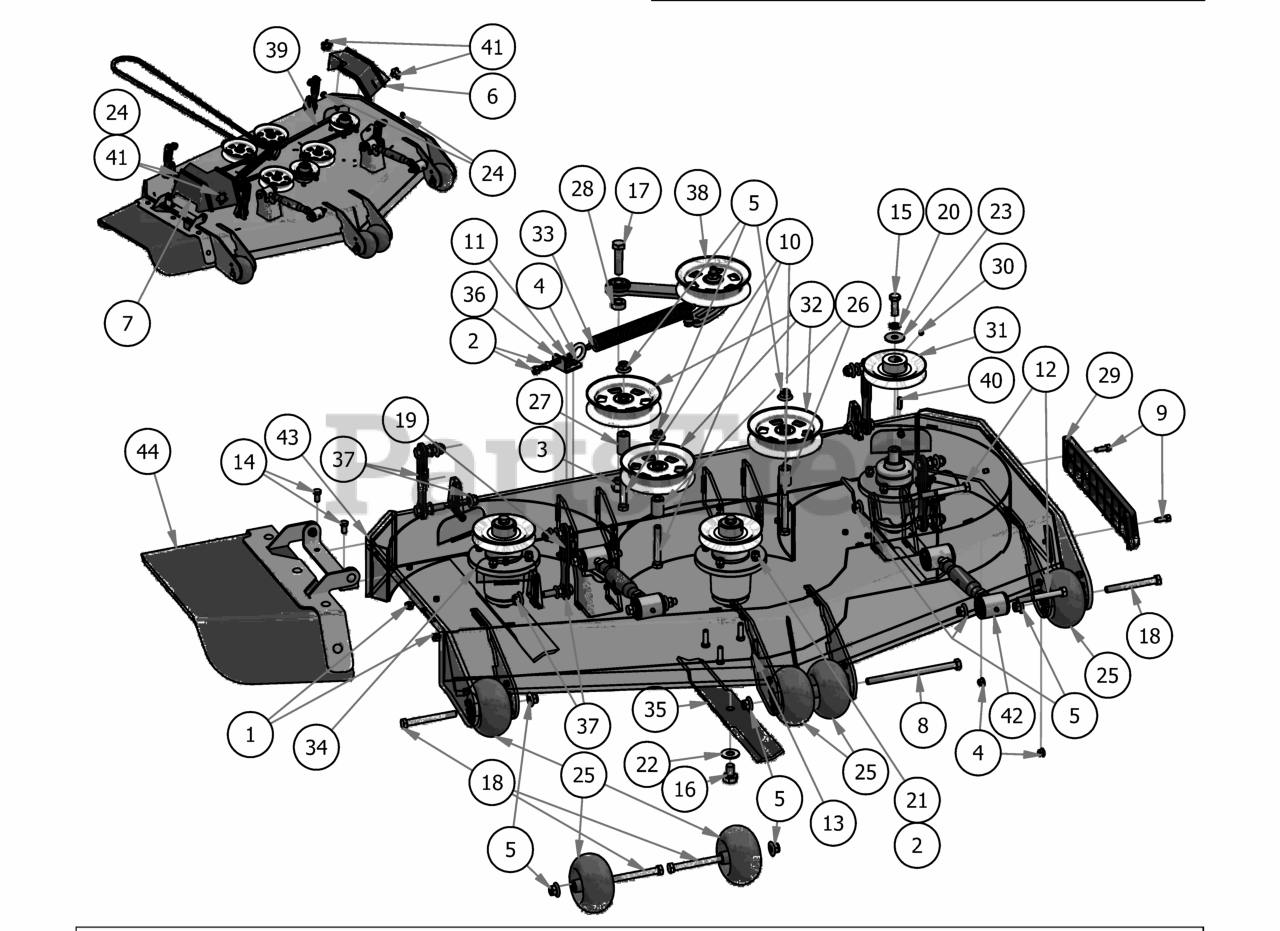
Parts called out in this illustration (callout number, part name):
1	3/8" Flange Nut
2	3/8" Hex Nut
3	5/8 Std NC Nylock Nut
4	5/16" Nylon Flange Nut
5	1/2-13 Nylon Flange Nut
6	2019 54" Left Outlaw Gen2 Pulley Cover
7	2019 54" Right Outlaw Gen2 Pulley Cover
8	1/2-13 x 8 Hex Bolt Grade 5
9	5/16-18 x 1 GR 5 Hex Bolt Zinc
10	1/2 x 3 1/2 Flange Bolt Grade 8
11	4" 3/8-16 Eye Bolt
12	1/2" x 4" Bolt (Grade 8)
13	3/8" x 1 1/4" Hex Bolt
14	3/8" x 3/4" Hex Bolt
15	1/2"-20 x 1 1/2 - Grade 5 Fine Thread Bolt
16	5/8" x 1 1/2" Grade 8 Hex Bolt (Fine)
17	5/8" x 2 1/2" Grade 5 Hex Bolt (Coarse)
18	1/2" x 4 1/2" Bolt
19	5/16" x 7/8" Carriage Bolt
20	1/2" Lock Washer
21	3/8" Lock Washer
22	5/8'' Flat Washer
23	1/2" Belleville Washer
24	.360 ID Plastic Washer-Black
25	2019 Deck Wheel
26	.502 ID X .750 OD X 1.500 Long Spacer
27	1 3/4" Pulley Spacer
28	5/8" x 1/" Collar W/One Set Screw
29	REVISED TRIM BUMPER_20180226
30	5/16 Set Screw
31	5.25" Deck Spindle Pulley
32	5-3/4 Idler Pulley
33	2019 Outlaw Gen2 Deck Spring
34	OUTLAW SPINDLE ASSEMBLY
35	54" Deck Fusion Blade For Outlaw
36	2019 Deck Eye Bolt Tab
37	Deck Hangar Assembly
38	2019 Rebel Rogue Deck Idler
39	B165 Belt-60 54" deck Outlaw
40	1/4" x 1" Key
41	5/16" Knob
42	Turnbuckle
43	2019 Sloped 54" Deck
44	2019 Outlaw Gen2 Chute Assembly
